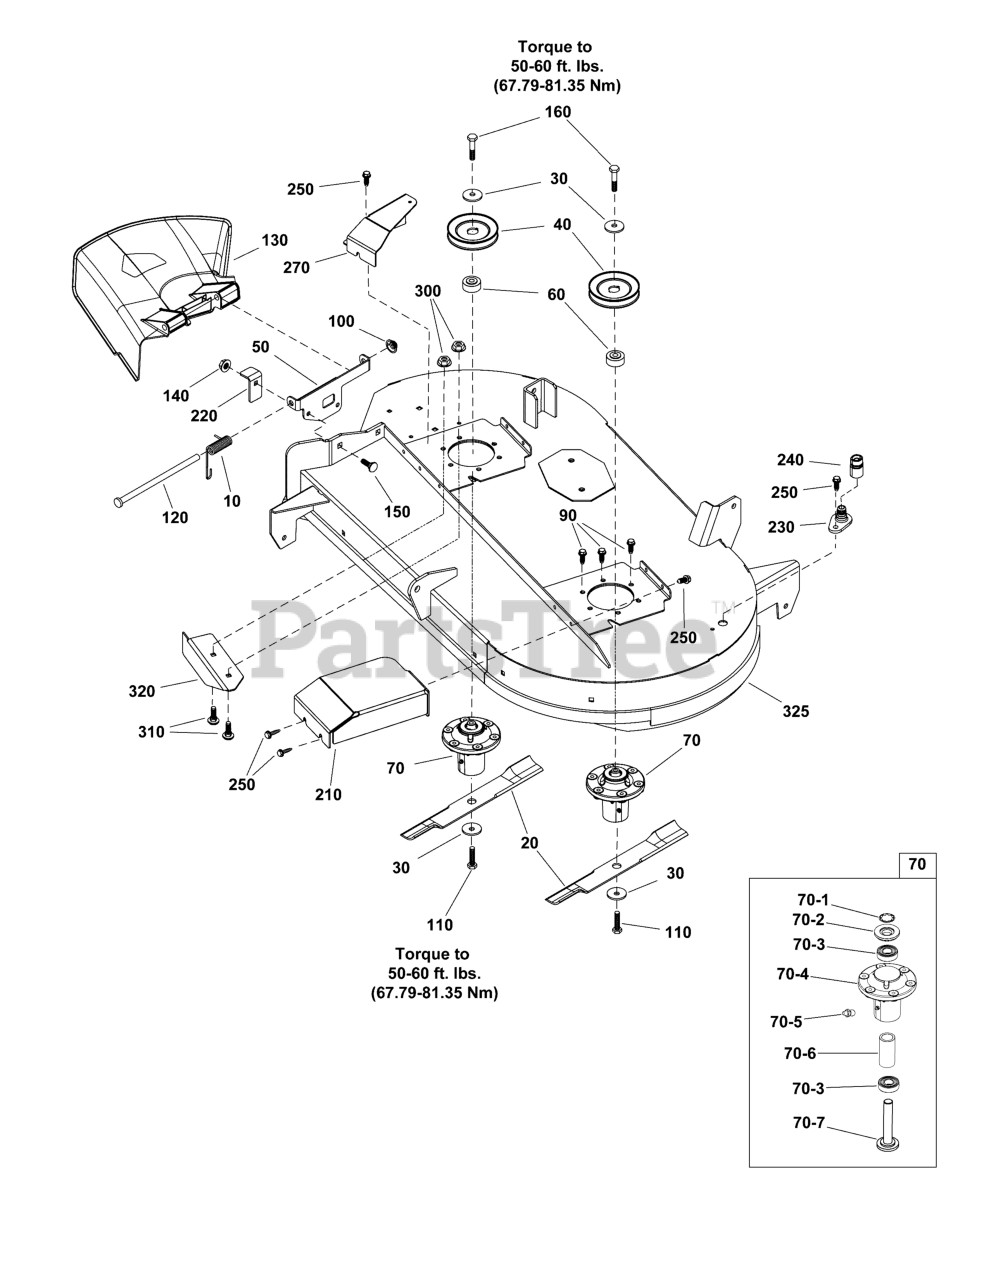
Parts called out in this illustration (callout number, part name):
10	SPRING, TORSION, SIDE
20	BLADE SET, 42" DECK (Set of 2 Blades)
30	WASHER, SPRING 0.475I
40	PULLEY, 4.50
50	BRACKET, DEFLECTOR
60	SPACER, Pulley
70	ARBOR ASSEMBLY
70-1	RING, SELF LOCKING
70-2	COVER, ARBOR
70-3	BEARING, Ball, 20mm
70-4	HOUSING ASSEMBLY
70-5	LUBE FITTING, .250 DR
70-6	SPACER, BEARING
70-7	SHAFT, SPINDLE
90	SCREW, HEX, 5/16-18X1
100	PUSHNUT, CAP TYPE
110	CAPSCREW-HEX HD 7/16-
120	ROD, Deflector
130	CHUTE, SIDE DISCHARGE
140	NUT, 3/8-16 HEX SERRA
150	BOLT, RD SQ 3/8-16X1
160	CAPSCREW
210	COVER, Pulley, LH
220	PROP, DEFLECTOR
230	KIT, WASHOUT PORT
240	WASHOUT PORT, Connector
250	SCREW, 5/16-18 X .75
270	COVER, Pulley, RH
300	NUT
310	RHSSNB
325	DECK SHELL W/ DECALS, 300S-42, USA
